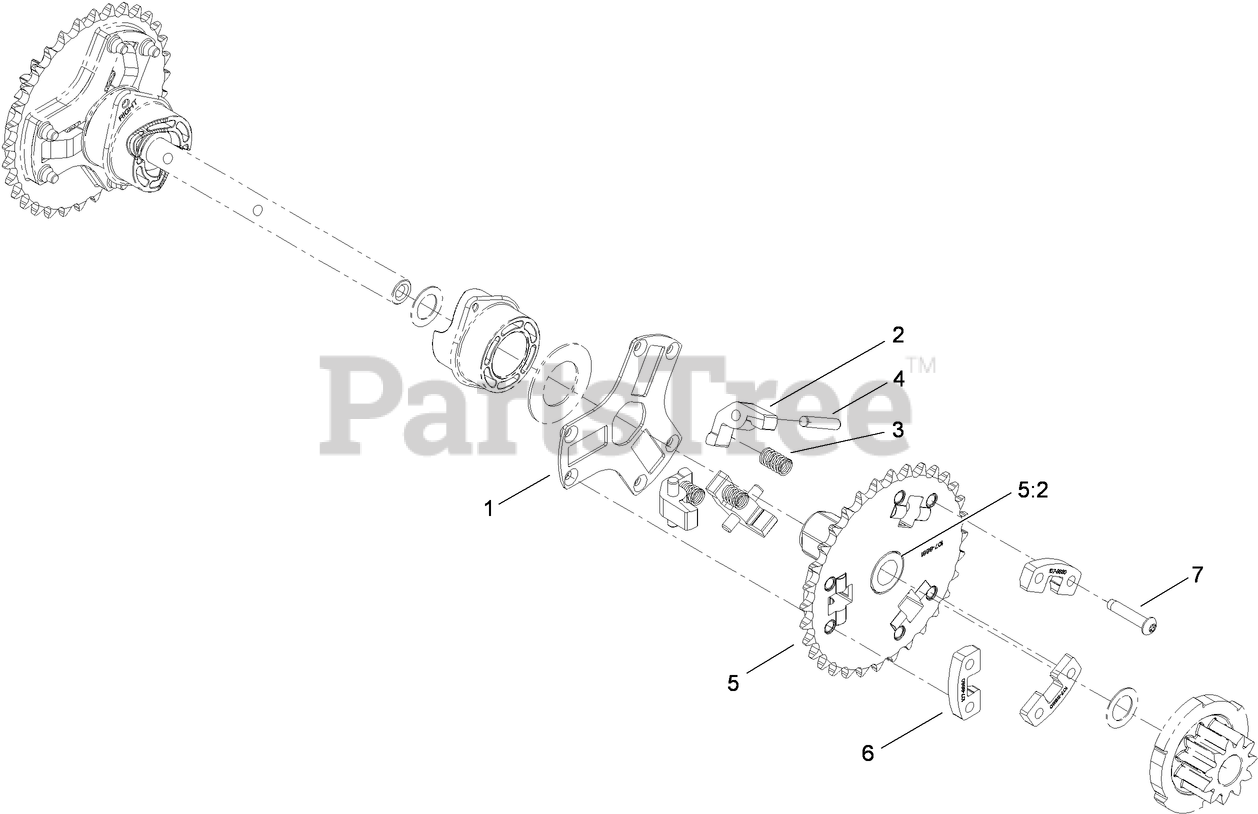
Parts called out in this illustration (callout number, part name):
1	RETAINER-PIN, PAWL
2	PAWL-CLUTCH
3	SPRING-COMPRESSION
4	PIN-DOWEL
5	32T SPROCKET ASM
5:2	BUSHING-FLANGE
6	SUPPORT-PAWL
7	SCREW-TTH, THREAD ROLLING
